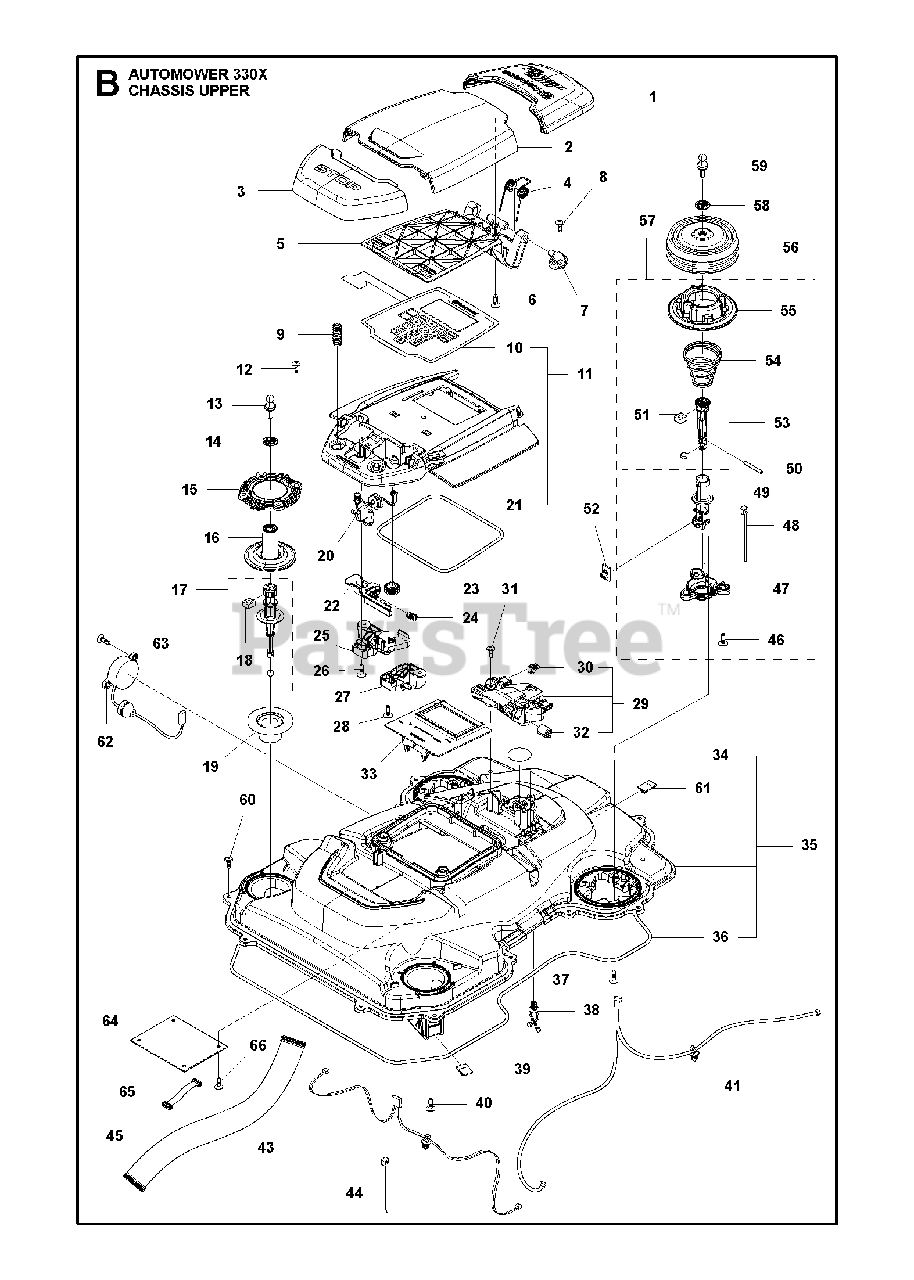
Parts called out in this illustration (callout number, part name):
2	HATCH ROBOTIC GREY
3	BUTTON STOP
6	SCREW 14MM
8	SCREW 14MM
11	COVER KIT DISPLAY ILLUMINATED
12	SCREW ITXPANT
13	STUD SNAPLOC
14	WASHER JOYSTICK
16	RUBBER GAITERS
17	COLUMN ASSY
18	NUT
19	MOVEMENT LIMITER
20	SWITCH STOP BUTTON
21	Sealing Strip
21	SEALING STRIP CHASSIS UPPER 10
24	SPRING LOCK STOP BUTTON
26	SCREW 14MM
28	SCREW 14MM
29	SUPPORT KIT FRONT
31	SCREW 14MM
34	KIT AIR FILTER KIT 305 - 10 PC
35	CHASSIS KIT UPPER
36	Sealing Strip
36	SEALING STRIP CHASSIS 10 PCS
37	SCREW ITXPANT
38	HOLDER TWIST LOCK
39	PRINTED CIRCUIT ASSY COLLISION
40	SCREW 14MM
41	LOOM KIT COLLISION SENSOR
43	LOOM KIT LIFT SENSOR
44	BAND
46	SCREW 14MM
48	BAND
51	NUT
52	PRINTED CIRCUIT ASSY PCBA LIFT
54	SPRING COLLISION JOYSTICK
55	RETAINER COLLISION SPRING
56	BELLOWS LIFT-COLLISION
58	WASHER JOYSTICK
59	STUD SNAPLOC
60	SCREW ITXPANT
61	PRINTED CIRCUIT ASSY COLLISION
63	SCREW 14MM
64	PRINTED CIRCUIT ASSY GPS BOARD
66	SCREW 14MM
